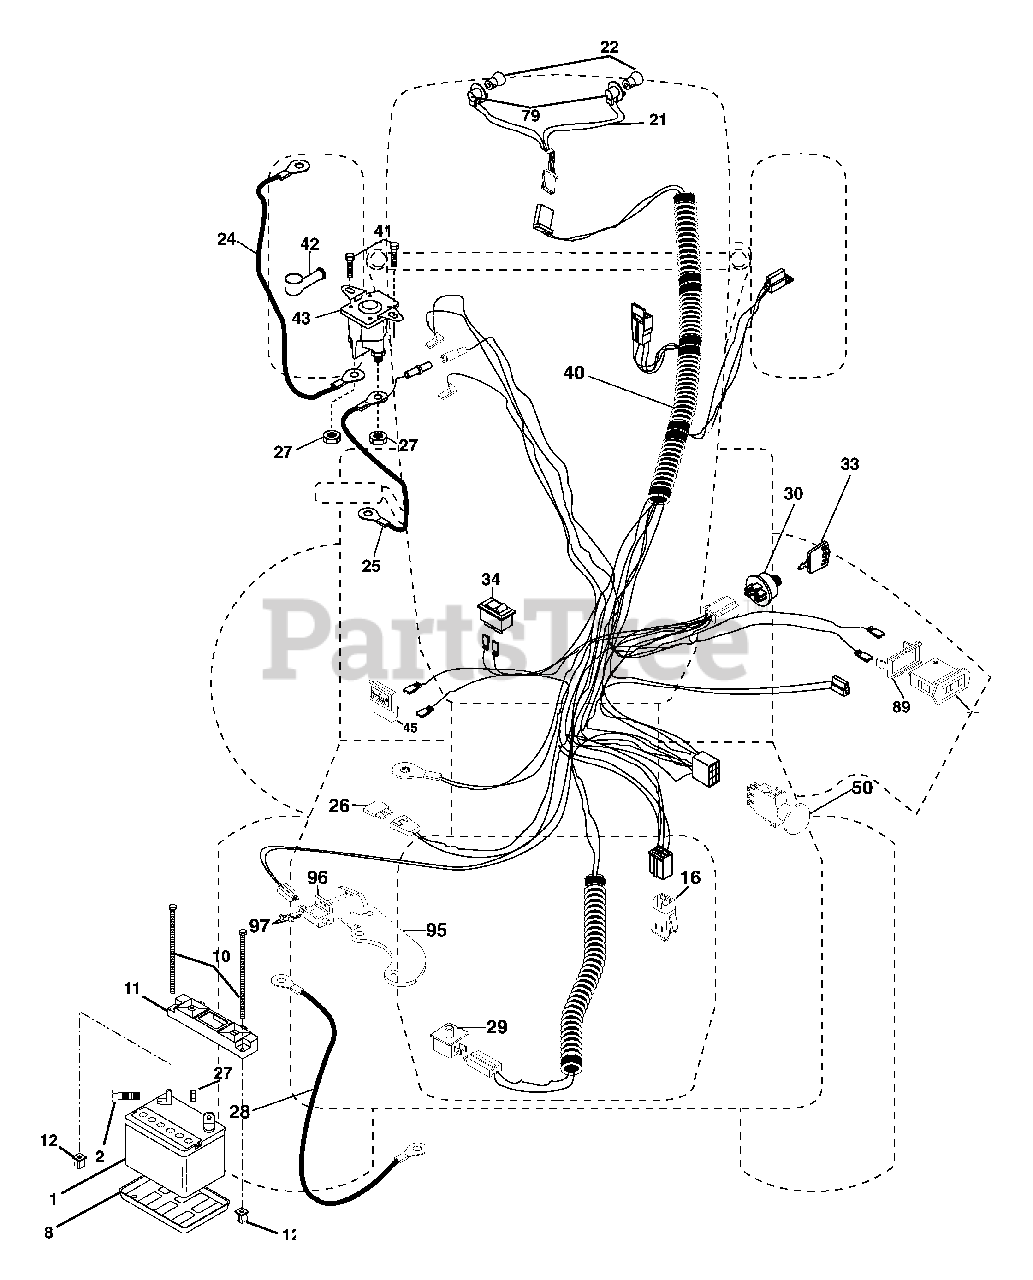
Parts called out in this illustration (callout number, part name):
1	Battery
2	Bolt Hex Head 1/4-20 x 3/4
8	Tray, Battery
10	Bolt 1/4-20 x 7.5 Zinc
11	Hold down Battery Dash Mount
12	Nut Push Nylon 1/4"
16	Switch Interlock Push-In
21	Harness Socket Light W/4152J
22	Bulb Light
24	Cable Battery
25	Cable, Battery
26	Fuse
27	Nut Keps Hex 1/4-20 unc
28	Cable, Ground
29	Switch, Plunger
30	Switch, Ign
33	Key, Ignition
34	Switch Light / Reset
40	Harness Ign.
41	Screw Thd. Cut 1/4-20 x 1/2
42	Cover, Terminal
43	Solenoid
45	Ammeter
50	Switch, PTO
79	Bulbholder Asm. Incan Descent
95	Bracket ROS
96	Switch Interlock
97	Screw Hex Wsh Slt 10-24 x .50
